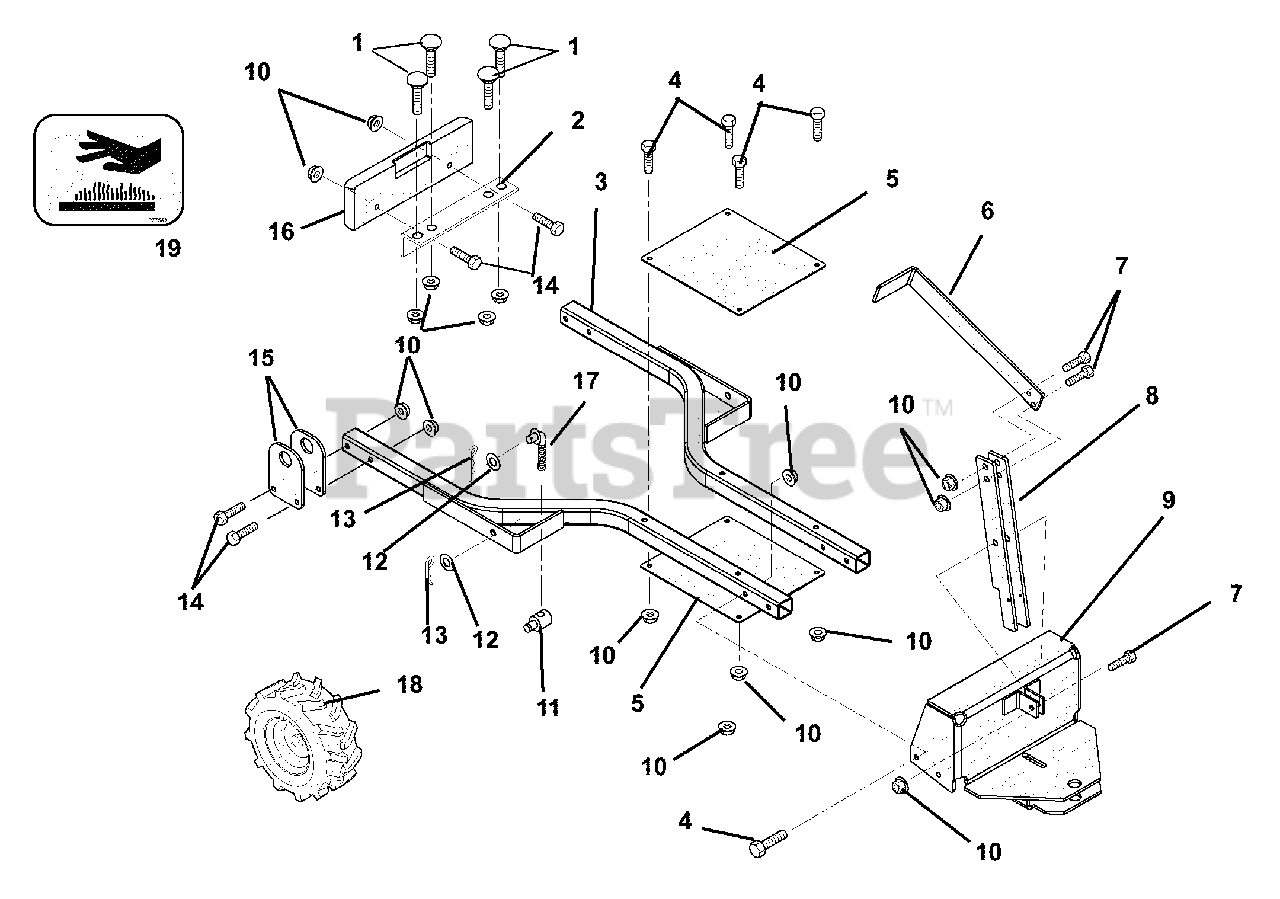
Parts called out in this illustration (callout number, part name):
1	Bolt-Round Head Square Neck, .38-16 x 2.50 Grade 5
2	Angle Bracket
3	Sub-Frame Tube
4	Hex Bolt, .38-16 x 2.25 Gr 5
5	Sub-Frame Plate
7	Hex Bolt, .38-16 x 1.25 Gr 5
9	Blade Mount Yoke
10	Top Locking Flange Nut, .38-16
11	Trunnion
12	Flat Steel Washer, .531 x 1.250 x .100
13	External Hair Pin - #16 Black Zinc
14	Hex Bolt, .38-16 x 2.5 Gr 5
15	Pivot Bracket
16	Weight, Cast Iron
17	Lift Link
18	Tire/Wheel Assembly, 18 x 16.5
19	Decal, Hot Surface
